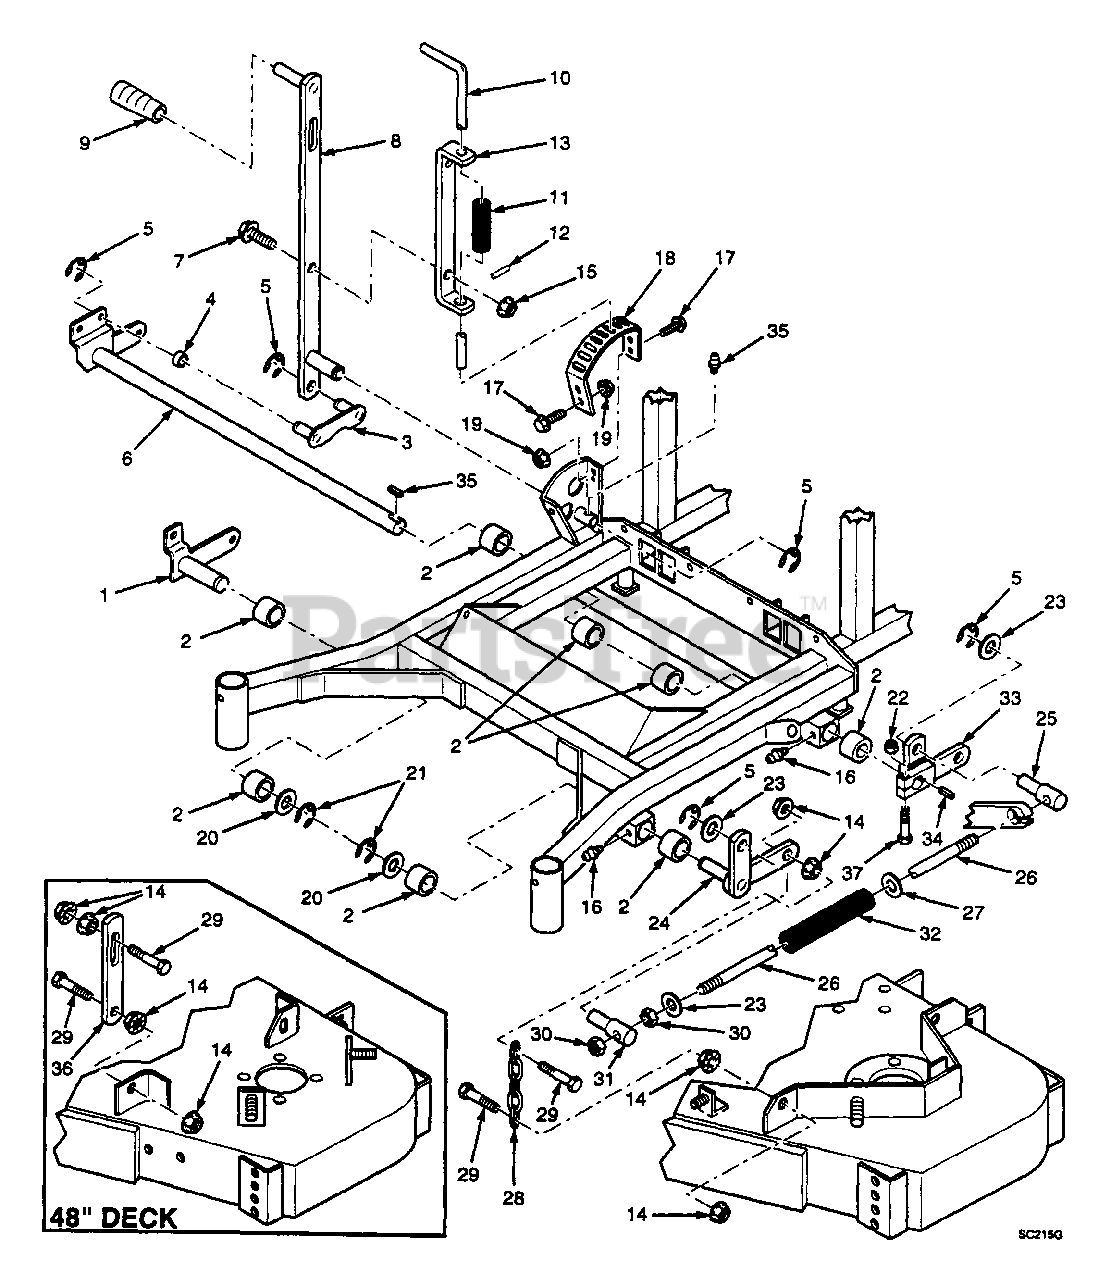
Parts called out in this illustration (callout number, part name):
1	Bellcrank. Lift-Right Front
2	Bushing
3	Lift Link
4	Bushing
5	Retaining Ring, 5/8" External "E"
6	Lift Arm Weldment
7	Bolt, Serrated Flange Hex Head 5/16-18 x 1"
8	Height Adjustment Lever
9	Grip, Lever Lift
10	Rod, Cutter Deck Lock
11	Spring, Deck Lift Index
12	Roll Pin, 5/32 x 3/4"
13	Lock, Rod Guide
14	Nut, Serrated Flange Hex 3/8-16
15	Nut, Serrated Flange Hex 5/16-18
16	Grease Fitting
17	Bolt, Serrated Flange Hex Head 1/4-20 x 3/4"
18	Strip, Height Adjustment
19	Nut, Serrated Flange Hex 1/4-20
20	Flatwasher, 3/4 (.766 x 1.250 x .075)
21	Ring, Retaining 3/4" External "E"
22	Nut, Elastic Stop 3/8-16
23	Flatwasher, 5/8 (.656 x 1.312 x .075)
24	Bellcrank, Lift-Left Front
25	Swivel Joint - LH THD
26	Adjustment Stud
27	Flatwasher, 5/8" (.688 x 1.75 x .134)
28	Chain
29	Bolt, Hex Head 3/8-16 x 1-1/2"
30	Nut, Hex 5/8-11
31	Swivel Joint - RH
32	Spring, Deck Lift
33	Bellcrank
34	Key, 3/16 x 3/16 x .75"
35	Grease Fitting
36	Link, Deck Support
37	Bolt, Hex Head 3/8-16 x 2"
